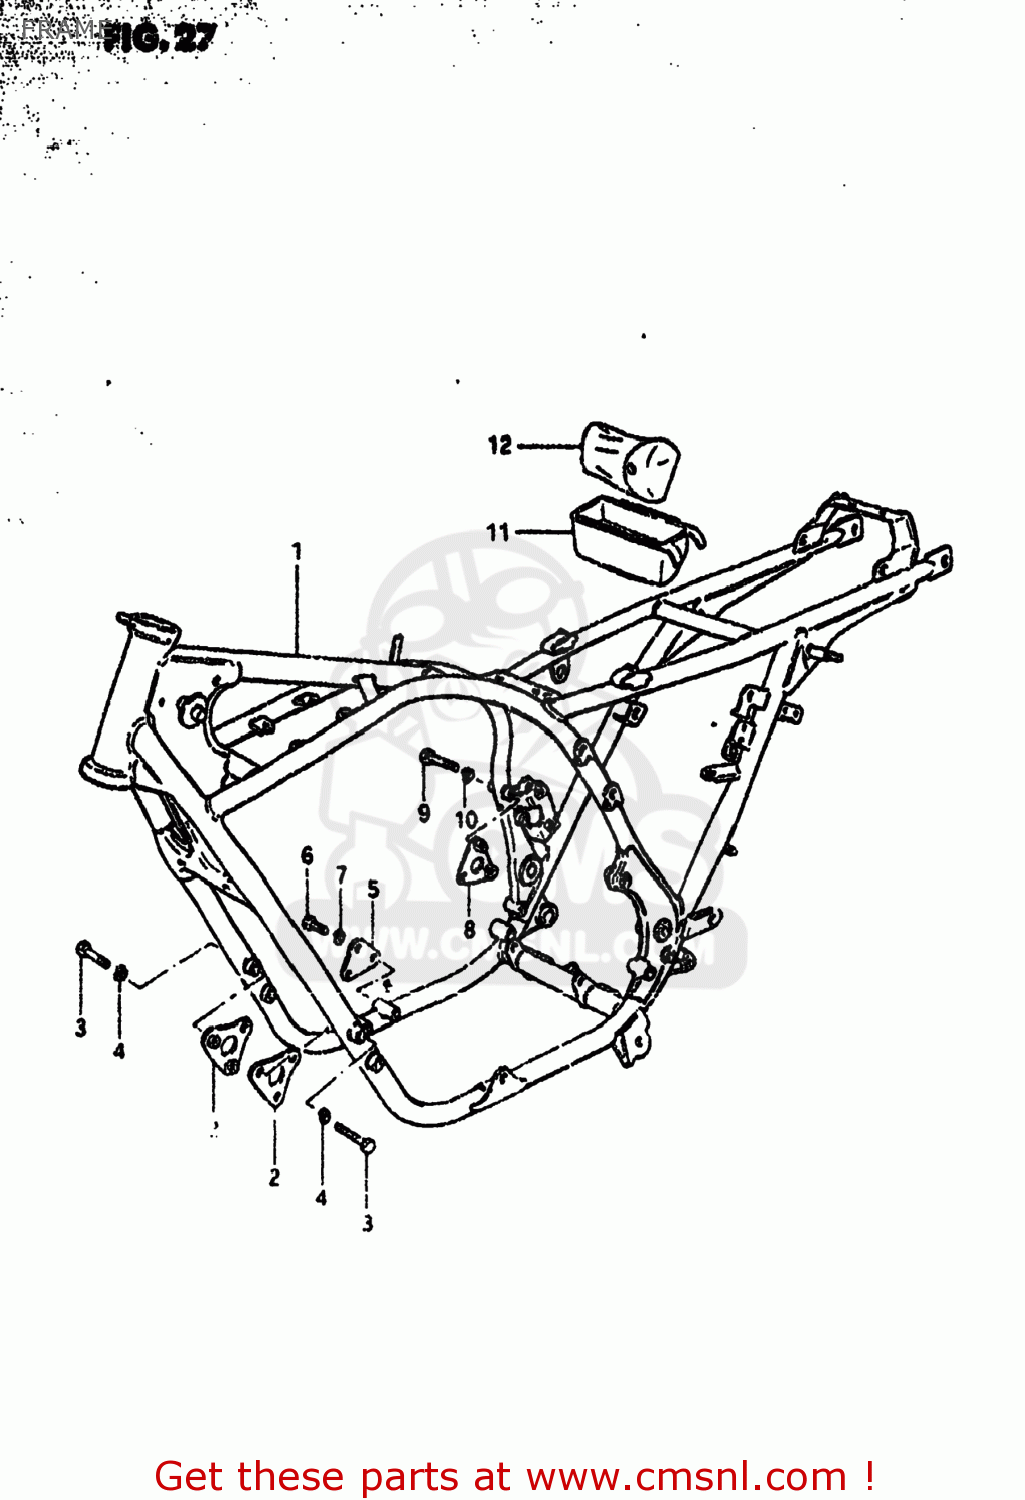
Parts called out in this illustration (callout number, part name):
1	FRAME
2	PLATE,ENGINE MOUNTING
3	BOLT
4	LOCK WASHER
5	PLATE,ENGINE MOUNTING
6	BOLT
7	LOCK WASHER
8	PLATE,ENGINE MOUNTING
9	BOLT 8X55
10	LOCK WASHER
11	HOLDER,TOOL
12	TOOL SET
